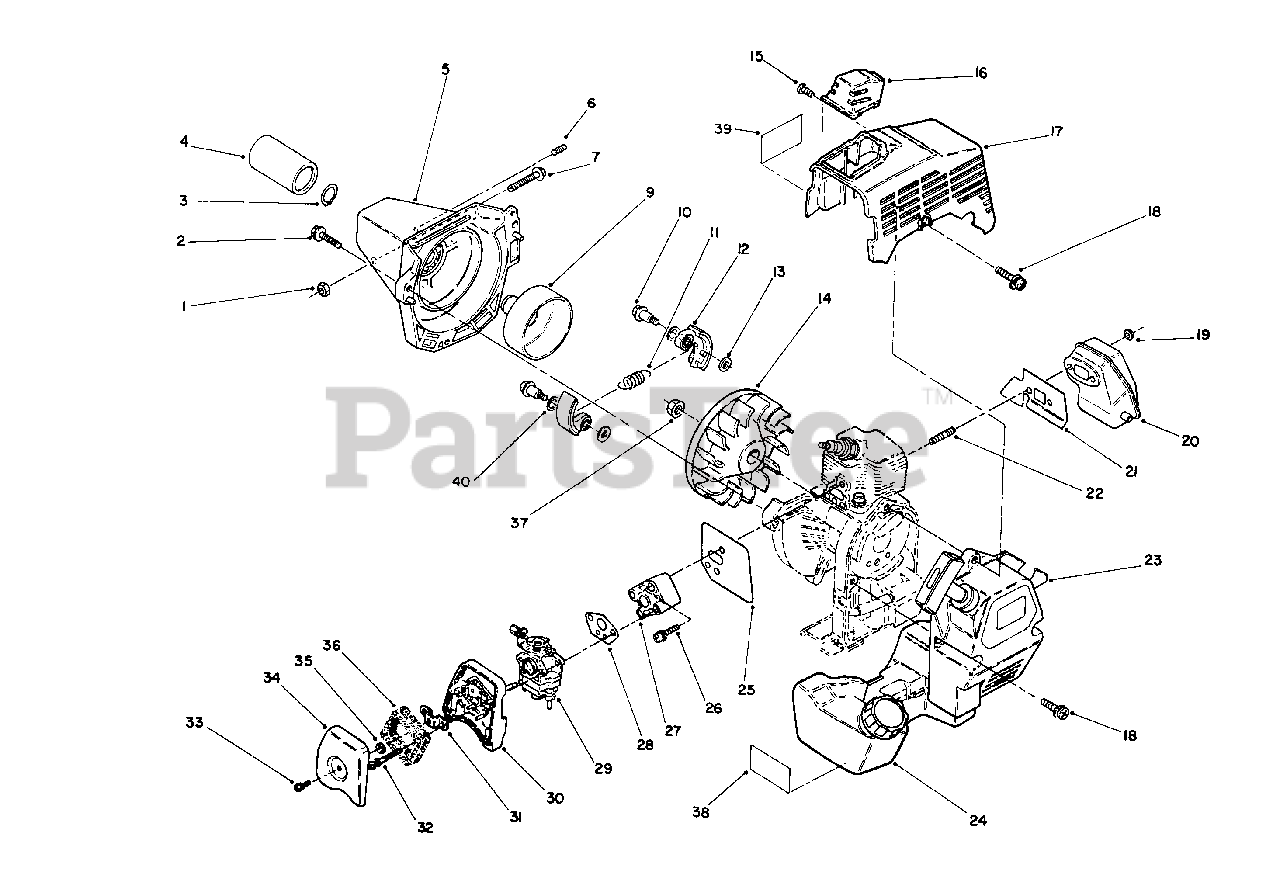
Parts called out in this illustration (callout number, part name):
1	Nut-Lock
2	Bolt/Washer
3	Ring-Retaining
5	Housing-Clutch
6	Screw-Set
7	Screw/Washer
9	Clutch-Drum
10	Bolt Clutch
11	Spring
12	Shoe-Clutch
14	Fan
16	Guard-Spark Plug
17	Cover-Engine
18	Screw/Washer
19	Nut-Flanged
21	Gasket-Muffler
23	Recoil Assembly
24	Fuel Tank Assembly
25	Gasket-Insulator
26	Screw/Washer
27	Insulator
28	Gasket-Carburetor
29	Carburetor Assembly
30	Case-Air Cleaner
31	Bracket-Cover
32	Screw/Washer
33	Screw/Washer
34	Cover-Air Cleaner
36	Element-Air Cleaner
37	Nut-Conical
38	Decal-Mix
39	Decal-Hot
40	Washer-Wave
